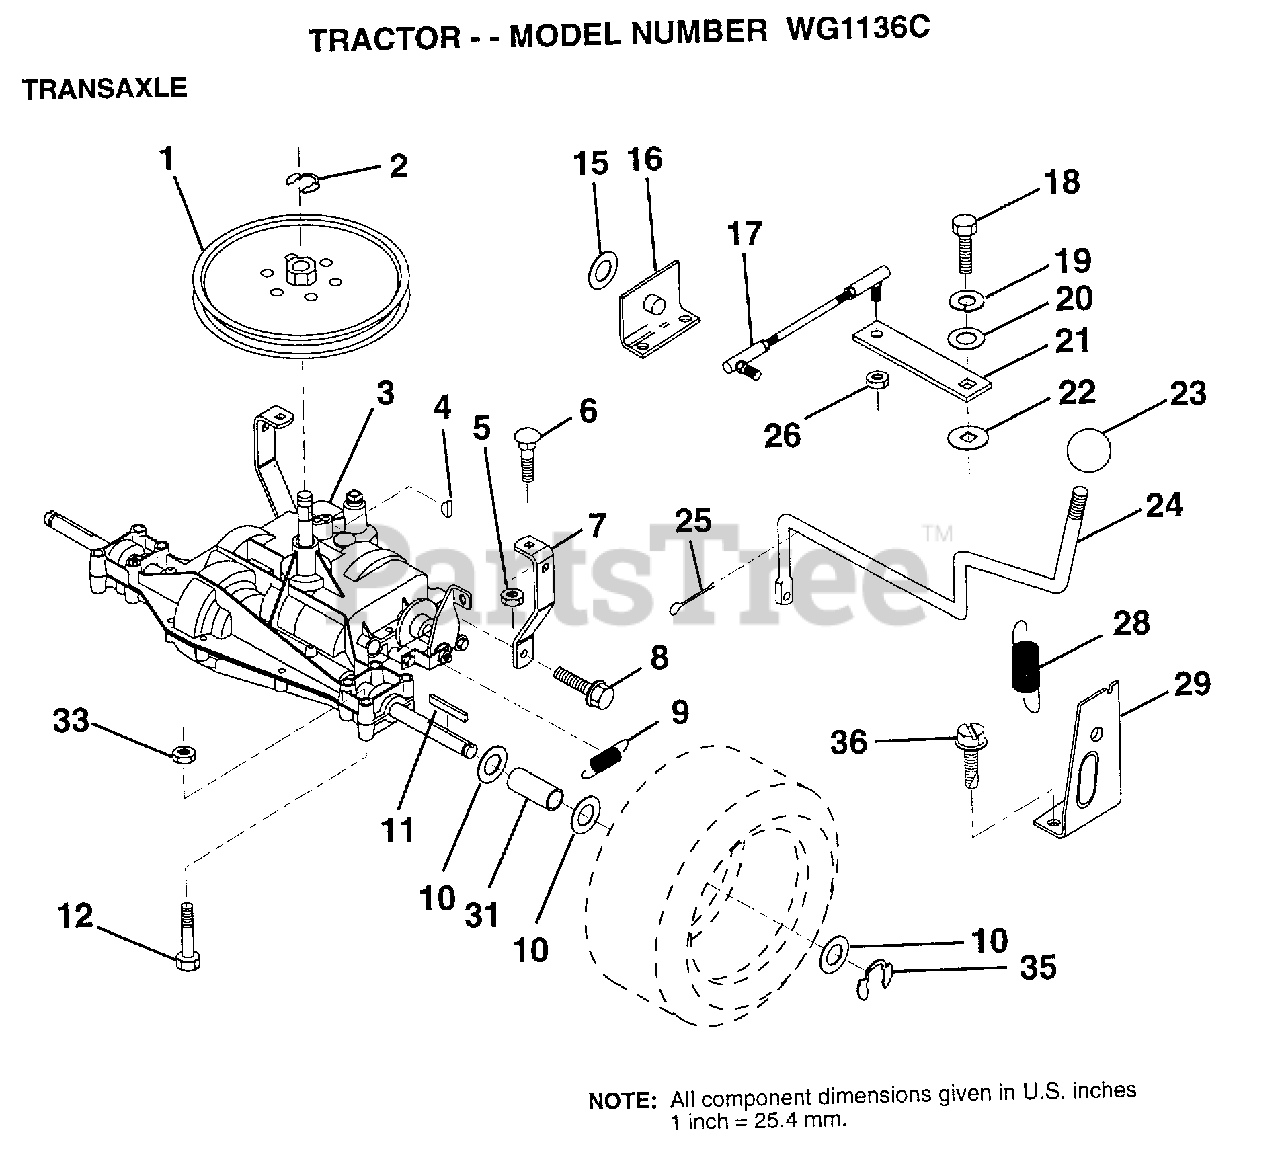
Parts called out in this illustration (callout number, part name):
1	PULLEY
6	BOLT
7	"STRAP,TORQUE"
8	SCREW
9	SPRING.BRAKE.RETU
10	WASHER
11	SQUARE KEY
12	BOLT
16	"SUPT,HDLE SHT LH"
17	"LINK,SHIFT"
18	BOLT.1/4-28.W/PAT
19	LOCKWASHER
20	WASHER LT
21	ARM SHIFT
22	WASH-SHFT PLT LT
23	KNOB T (1/2-HOLE)
24	"ROD,SHIFT"
25	PIN COTTER 1/8
26	NUT.LOCK.5/16-24
28	"SPRING,EXT"
29	"SUPT,HDLE RH"
31	SPACER LT
35	E-RING LT
36	SCREW
